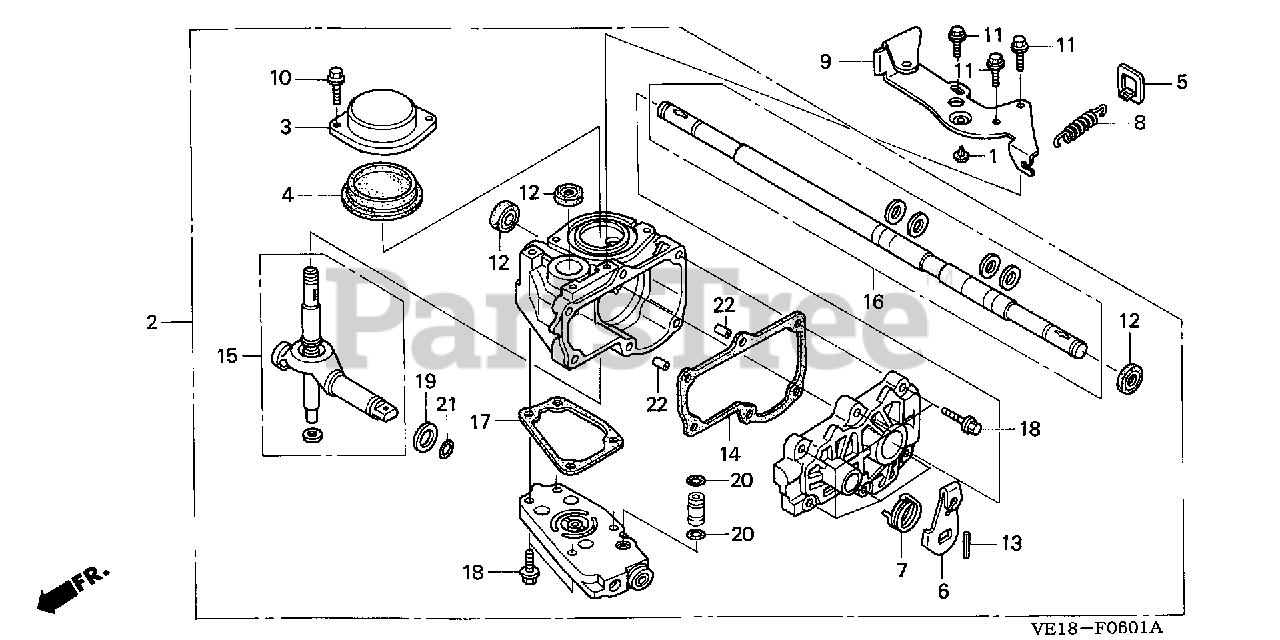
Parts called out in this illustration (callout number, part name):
1	RUBBER, TANK STOPPER
2	TRANSMISSION ASSY.
3	CAP, OIL
4	GASKET, OIL CAP
5	PLATE, TENSION SPRING
6	ARM, CONTROL
7	SPRING, CONTROL ARM RETURN
8	SPRING, WHEEL TENSION
9	HOLDER, WIRE
10	BOLT, FLANGE (5X12)
11	BOLT, FLANGE (6X16) (CT200)
12	OIL SEAL (13X22X5) (ARAI)
13	PIN, SPRING (4X25)
14	GASKET, TRANSMISSION CASE
15	SHAFT SET, PUMP (NA USE ALT:20011-VE5-711)
16	SHAFT SET, MOTOR (NA USE ALT:20011-VE5-711)
17	GASKET, DISTRIBUTOR
18	BOLT, FLANGE (6X28)
19	WASHER, THRUST (16MM)
20	O-RING (7.3X1.9) (NA USE ALT:20011-VE5-711)
21	O-RING (11.8X2.6) (NA USE ALT:20011-VE5-711)
22	PIN, DOWEL (8X10)
